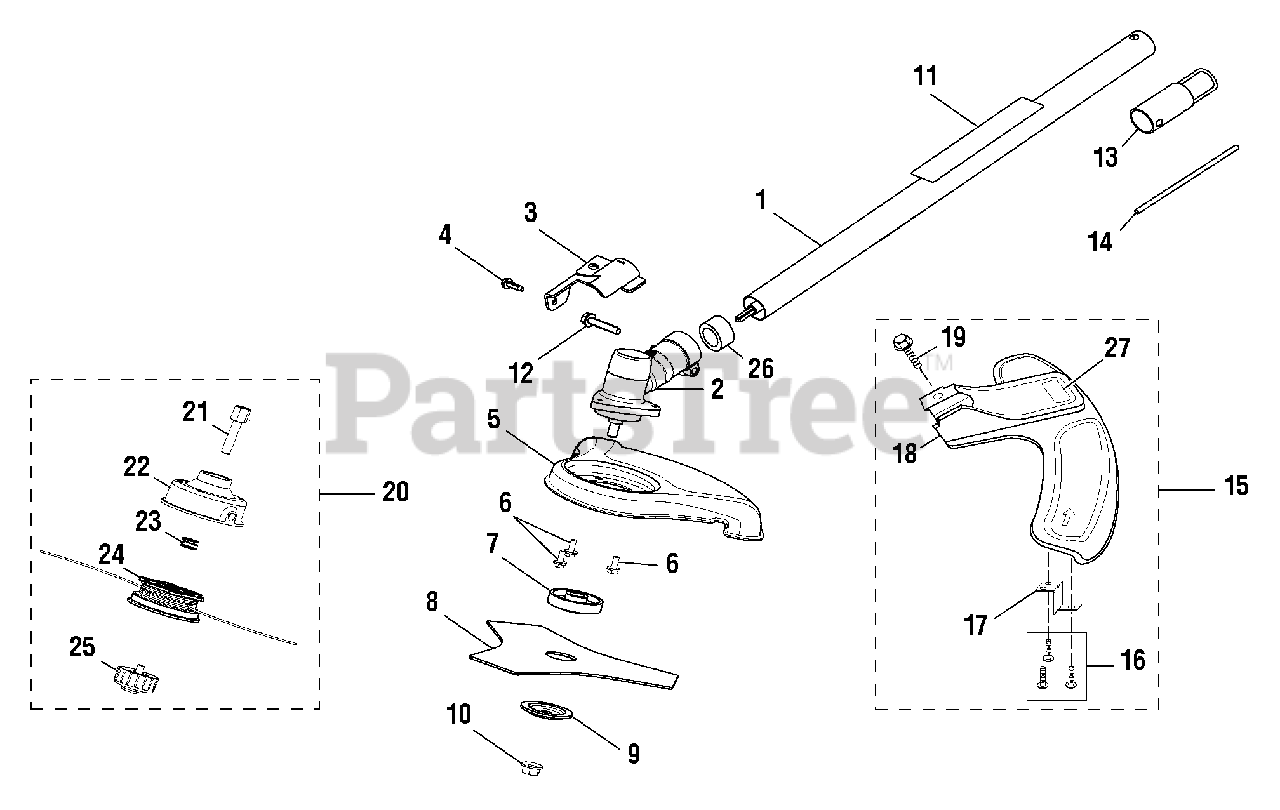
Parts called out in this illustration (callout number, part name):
1	STRAIGHT SHAFT ASSEMBLY
2	GEAR CASE ASSEMBLY
3	GRASS DEFLECTOR CLAMP
4	SCREW (#10-24 X 5/8 in. HEX WASHER HD.)
5	BLADE GUARD
6	SCREW (#10-24 X 1/2 in. SEMS SLOTTED HEX HD.)
7	FLANGED WASHER
8	BLADE (TRI-ARC(TM)) .
9	CUPPED WASHER
10	BLADE NUT, LEFT-HANDED THREADS
11	WARNING LABEL
13	HANGER CAP .
14	HEAD LOCKING TOOL
15	GRASS DEFLECTOR ASSEMBLY
17	LINE CUTTING BLADE
18	GRASS DEFLECTOR
19	SCREW (#1/4-20 X 1-1/4 in. HEX WASHER HD.)
20	TRIMMER HEAD ASSEMBLY .
21	TRIMMER HEAD SHAFT ADAPTOR
22	TRIMMER HEAD
23	COMPRESSION SPRING .
24	SPOOL WITH LINE (.095) .
25	RETAINING CAP, LEFT-HANDED THREAD .
26	SPACER .
27	GRASS DEFLECTOR LABEL
